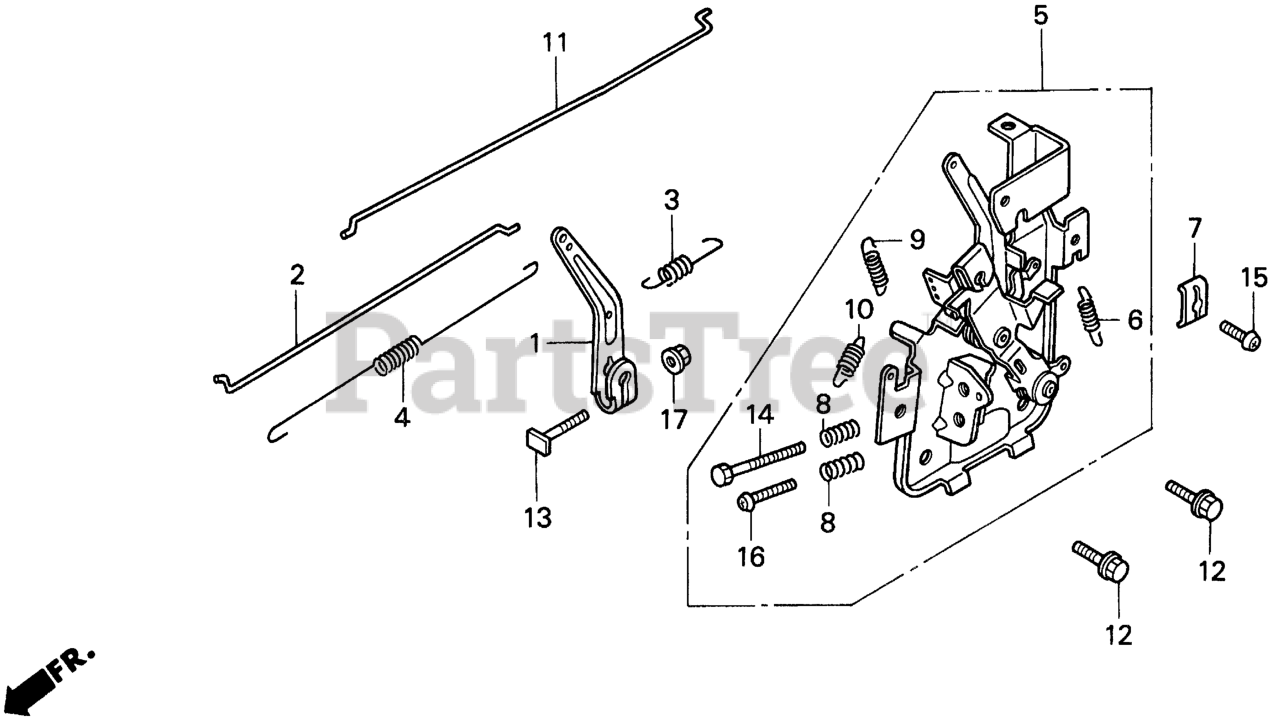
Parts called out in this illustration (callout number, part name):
1	ARM, GOVERNOR
2	ROD, GOVERNOR
3	SPRING, GOVERNOR
4	SPRING, THROTTLE RETURN
5	CONTROL ASSY.
6	SPRING, LEVER
7	HOLDER, CABLE
8	SPRING, CONTROL ADJUSTING Use from Engine SN 2327377.
9	SPRING, CONTROL LEVER RETURN
10	SPRING, CABLE RETURN
11	ROD, CHOKE
12	BOLT, FLANGE (6X12) (CT200)
13	BOLT, GOVERNOR ARM
14	BOLT, RECESSED (5X34)
15	SCREW, PAN (5X16)
16	SCREW, PAN (5X25)
17	NUT, FLANGE (6MM)
